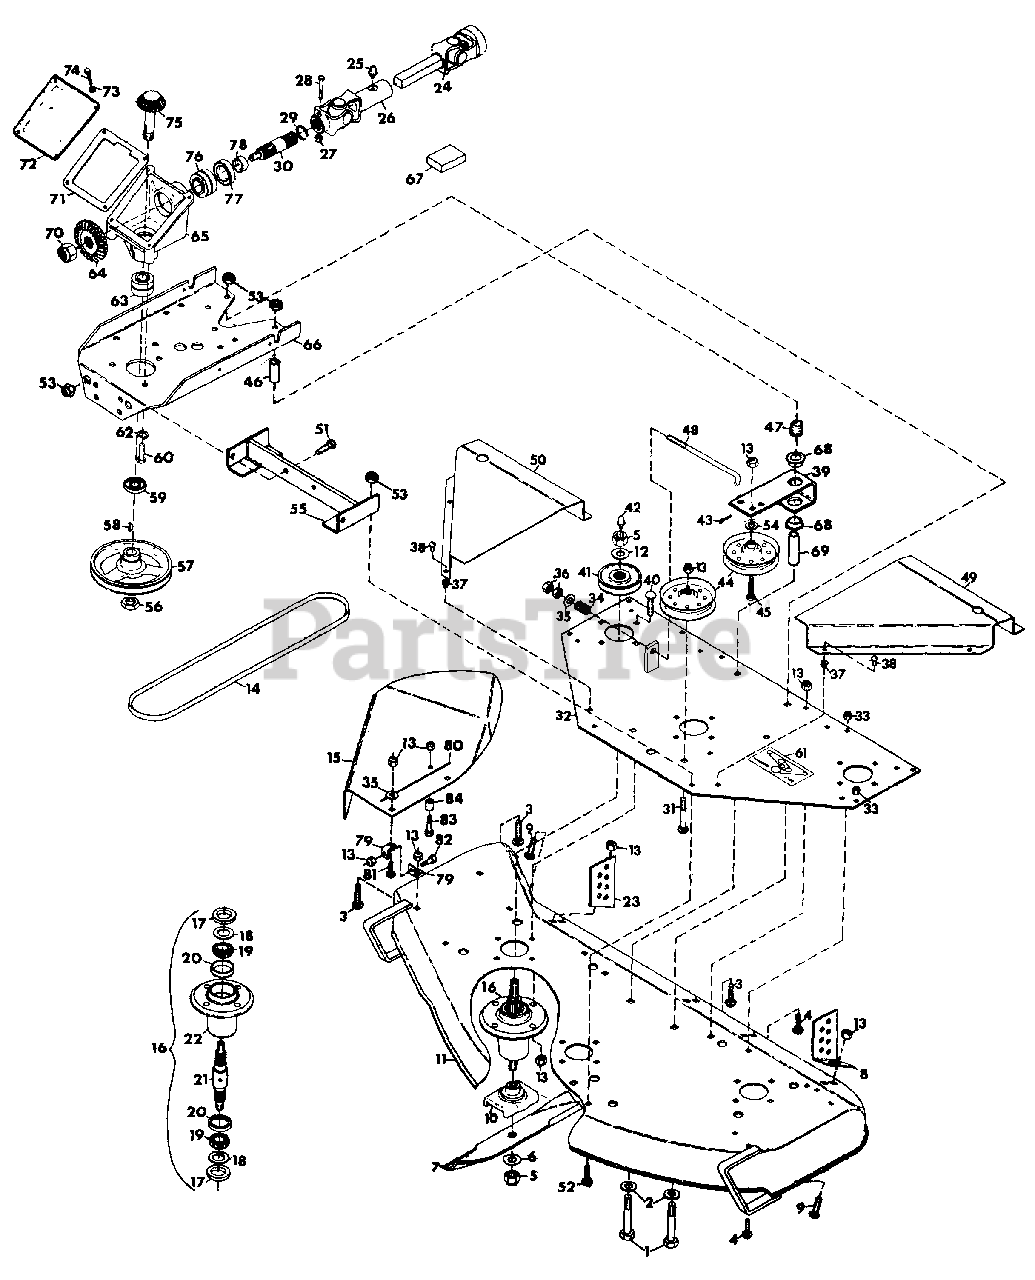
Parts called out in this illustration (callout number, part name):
1	BOLT, HEX 1/2-13X3.75
2	WASHER, FLAT .531X1.062X.095
3	BOLT, 3/8-16X.75 RD. HD. SQ. NK.
4	BOLT, 5/16-18X.75 RD. HD. SQ. NK.
5	NUT, LOCK 5/8-11
6	WASHER, FLAT .656X1.312X.095
7	BLADE
8	PLATE, REAR ADJUSTMENT
9	BOLT, HEX 3/8-16X1.25
10	CRADLE, BLADE
11	WELDMENT, PRO MASTER 50 INCH DECK
12	WASHER, FLAT .687X1.312X.122/.146
13	NUT, LOCK 3/8-16
14	BELT, V .500X.312X126.3
15	SHIELD, SAFETY EXTENSION 50 INCH MOWER
16	ASSEMBLY, SPINDLE
17	SEAL, STEEL
18	WASHER, FLAT .975X1.970X.030
19	ASSEMBLY, BEARING
20	SPACER
21	SHAFT, SPINDLE
22	HOUSING, BEARING
23	PLATE, REAR ADJUSTMENT
24	SHAFT, PROP. SQ. BAR
25	FITTING, LUBE 1/4-28
26	U-JOINT, FEMALE END
27	NUT, LOCK 1/4-20
28	BOLT, HEX 1/4-20X2
29	RING, RETAINING 1.000 SHAFT
30	SHAFT, DRIVE
31	BOLT, 3/8-16X1.75 RD. HD. SQ. NK.
32	WELDMENT, DECK SUPPORT PLATE
33	NUT, LOCK 5/16-18
34	SPRING, COMP. TYPE 1X.78X338 LB/IN
35	WASHER, FLAT .406X.812X.065
36	NUT, HEX 3/8-24
37	GROMMET, PLASTIC
38	SCREW, TAPPING 1/4-20X.5
39	ARM, IDLER PIVOT
40	BOLT, 3/8-16X1.25 RD. HD. SQ. NK.
41	SHEAVE, SPINDLE
42	FITTING, LUBE 1/8(LEFT AND RIGHT SPINDLE)
42	FITTING, LUBE .125 EXT.(CENTER SPINDLE)
43	PIN, COTTER 3/32X1.00
44	SHEAVE, IDLER
45	BOLT, HEX 3/8-16X2
46	SPACER, .510X.840X2.43
47	SPRING, COMP.
48	ROD, IDLER
49	COVER, PULLEY L.H.
50	COVER, PULLEY R.H.
51	BOLT, HEX 1/2-13X1.375
52	BOLT, HEX 1/2-13X1.25
53	NUT, LOCK 1/2-13
54	SPACER, IDLER .406X.750X.188
55	BRACKET, HEIGHT ADJUSTMENT
56	NUT, JAM 3/4-10 HEX HEAVY
57	SHEAVE, 1/2X6.50
58	KEY, WOODRUFF .188X.625 HARD
59	SEAL, OIL 1.250X1.686X.313
60	BOLT, HEX 1/2-13X1.00
61	DECAL, BELT INSTALLATION
62	WASHER, LOCK 1/2
63	ASSEMBLY, BEARING .750X1.781X1.499
64	GEAR, BEVEL
65	CASTING, GEAR BOX
66	SUPPORT, GEAR HOUSING
67	KIT, REPAIR UNIVERSAL JOINT ROCKWELL STD.
67	KIT, REPAIR UNIVERSAL JOINT NEAPCO 1605X
68	BUSHING, NYLON .760X1.00X.600
69	SPACER
70	NUT, LOCK 3/4-10
71	GASKET, GEAR HOUSING
72	COVER, GEAR HOUSING
73	WASHER, LOCK 1/4
74	BOLT, HEX 1/4-20X.50
75	SHAFT, GEAR PINION
76	ASSEMBLY, BEARING 1.000X1.980X1.243
77	SEAL, OIL 1.250X1.987X.250
78	WASHER, FLAT .438X1.000X.083
79	TAB, SPRING
80	STRIPE
81	BOLT, 3/8-16X1.00 RD HD SQ NK
82	BOLT, HEX 3/8-16X.875
83	BOLT, HEX 3/8-16X1.50
84	STOP, CHUTE
NS	ASM, DRIVE 50" MOWER
NS	DECAL, DANGER HAND
NS	DECAL, DANGER FOOT
NS	DECAL, WARNING EYE
NS	DECAL, PRO MASTER-50 MOWER
